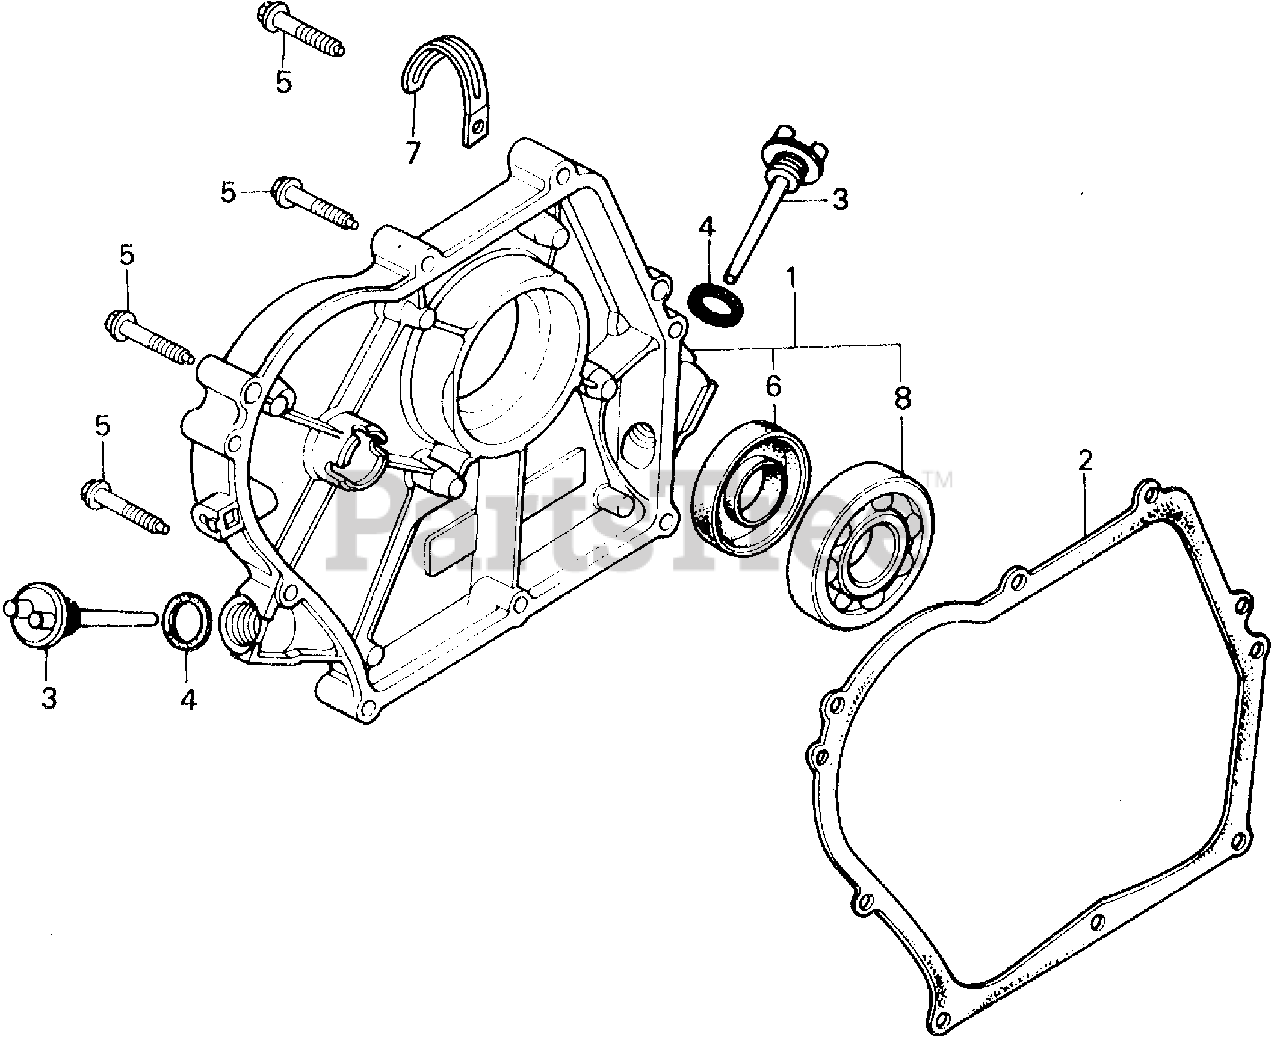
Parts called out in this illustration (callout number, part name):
1	COVER ASSY., CRANKCASE
2	GASKET, CASE COVER
3	CAP, OIL (YELLOW)
4	GASKET, OIL FILLER CAP
5	BOLT, FLANGE (6X32)
6	OIL SEAL (25X41X6)
7	CLIP, WIRE
8	BEARING, RADIAL BALL (6205)
